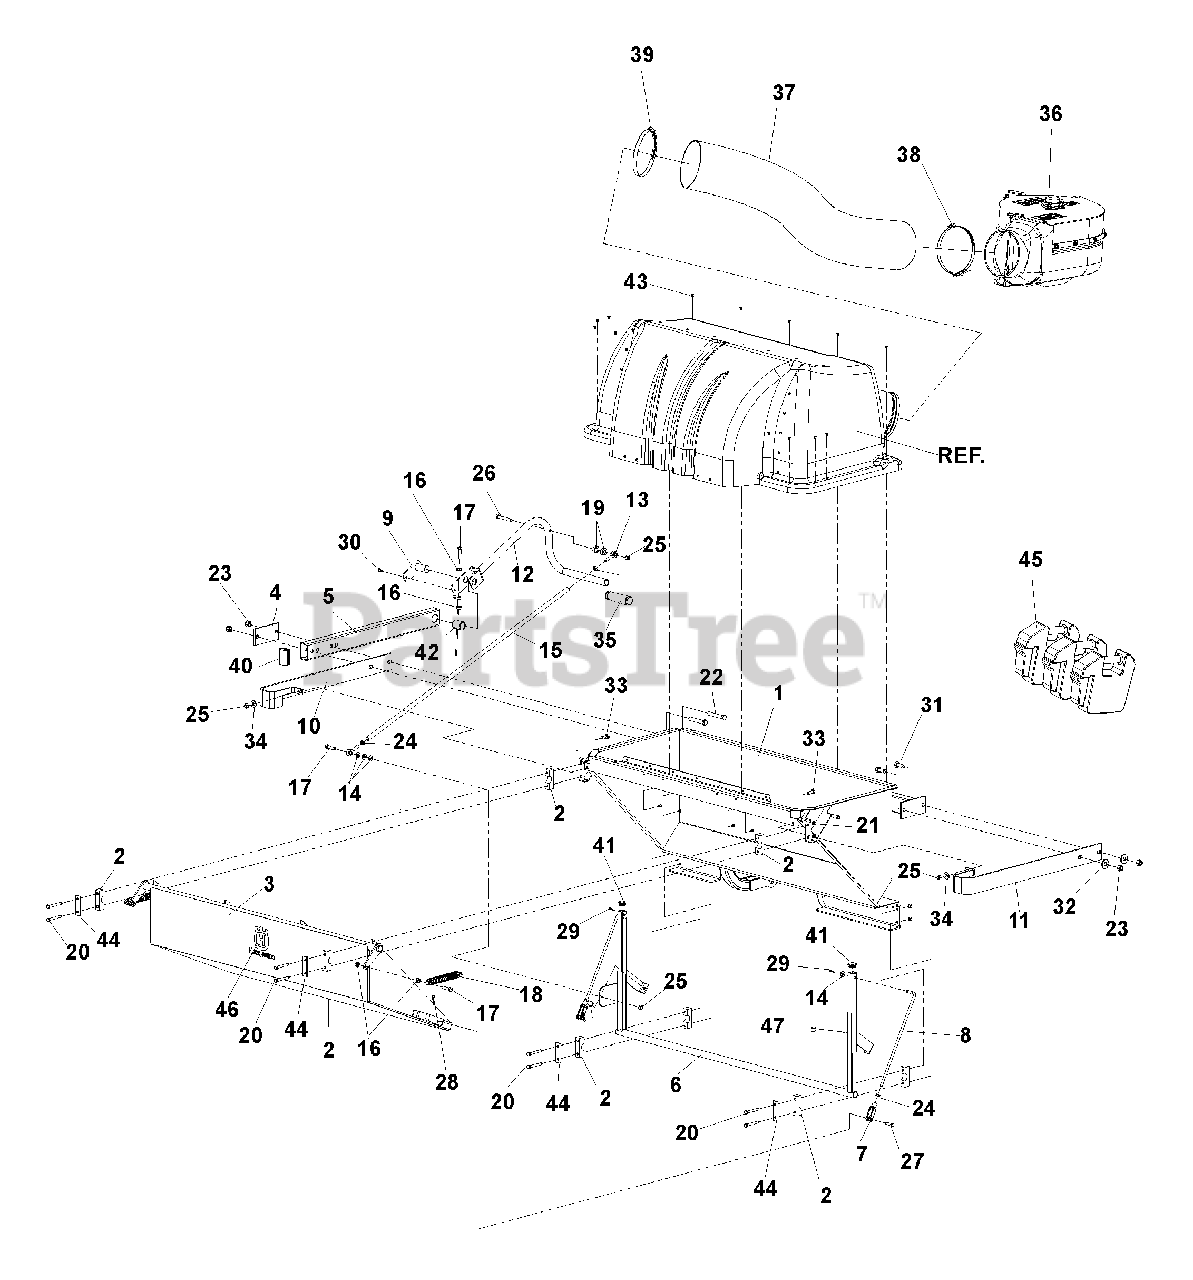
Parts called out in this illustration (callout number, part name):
2	PILLOW BLOCK
4	PLATE - BACKING
5	TUBE, SUPPORT, HANDLE
6	BELL CRANK
7	YOKE, 3/8F
9	PIN, PIVOT
10	GUARD, LEFT
11	GUARD, RIGHT
13	ROD END, 3/8-24, RH
14	WASHER, 3/8, SAE
15	TUBE, THREADED
16	NUT, 3/8-16, WHIZLK
17	HCS, 3/8-16 X 1 1/2, GR5
20	HCS, 5/16-18 X 2 1/2, GR5
21	NUT, 5/16-18, NYLOC
22	HCS, 1/2-13 X 3, GR5
23	NUT, 1/2-13, NYLOC
24	NUT, 3/8-24, JAM
25	NUT, 3/8-16, NYLOC
26	HCS, 3/8-16 X 2 3/4, GR5
27	PIN CLEVIS, 3/8 X 1 1/4
28	HAIRPIN COTTER
29	PIN, COTTER, 1/8 X 3/4
30	SCREW, 1/4C X 3/8, THREAD FORMING
31	HCS, 1/2-13 X 1 1/4, GR5
32	WASHER, 1/2
33	HCS, 3/8-16 X 1, GR5
34	WASHER, 3/8
35	GRIP, HANDLE
36	BLOWER
38	OVER CENTER BAND
39	HOSE CLAMP, 6"-7"
40	PLUG, RECTANGULAR TUBING
41	PLUG, SQUARE TUBE
42	BUSHING, 1"
43	RIVET, 3/6, STAVEX
44	REINFORCEMENT BAR
45	WEIGHT CAST, FRONT
46	DECAL, CROWN
47	GROMMET, BUMPER
